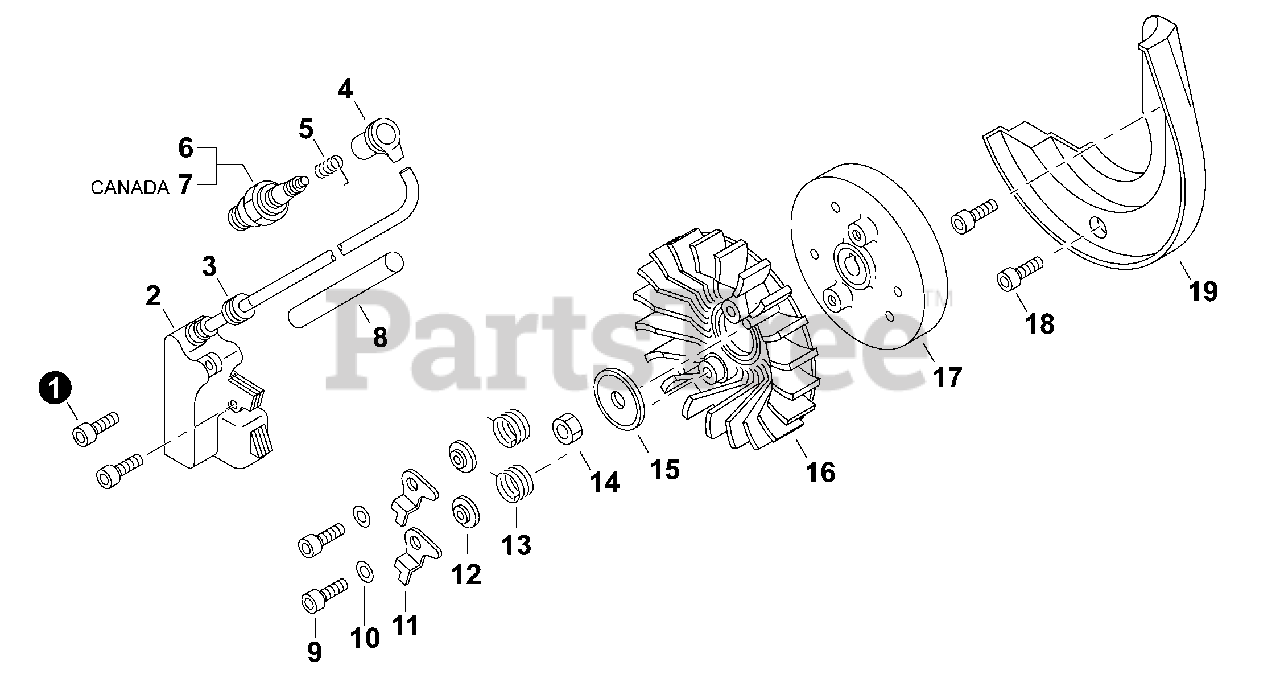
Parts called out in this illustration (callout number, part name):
1	BOLT 4×20
2	COIL, IGNITION
4	CAP, SPARK PLUG
5	TERMINAL, SPARK PLUG
6	SPARK PLUG - BPM7A
7	SPARK PLUG - BPMR7A
8	TUBE 7×8.6×45
9	BOLT 5×30
10	WASHER 5.5×12×0.8
11	PAWL, STARTER
12	SPACER, PAWL
13	SPRING, RETURN
14	NUT, FLANGE M8×1.25
15	WASHER 8.2×31×0.8
16	FAN, COOLING
17	FLYWHEEL
18	BOLT 5×20
19	PLATE, GUIDE - ORANGE
